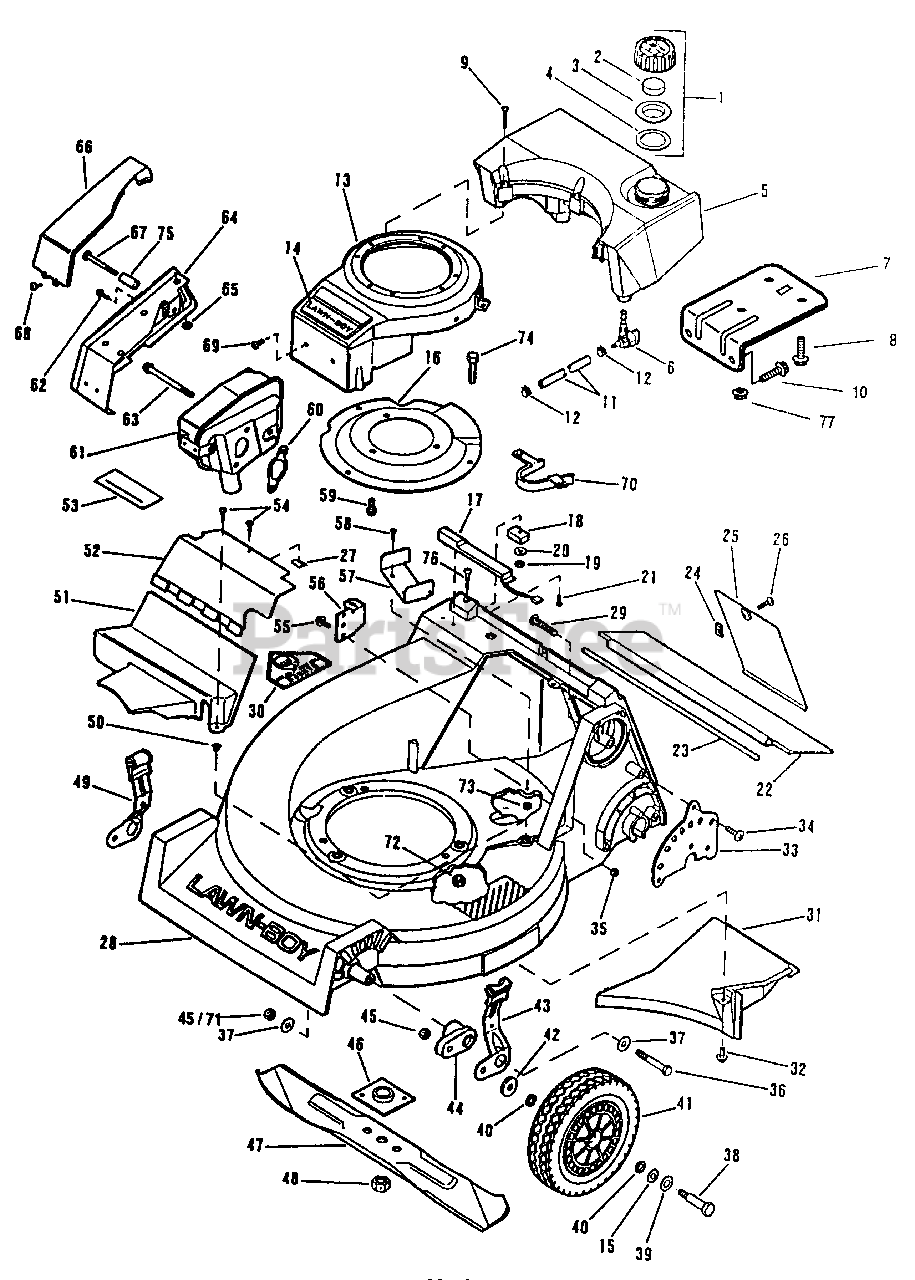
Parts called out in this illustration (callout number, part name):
1	Fuel Cap Assembly
2	Baffle
3	Cover
4	Gasket
5	Fuel Tank
6	Fuel Shut-Off Valve
7	Fuel Tank Mounting Bracket
8	Screw
9	Screw-Fuel Tank
10	Screw-Fuel Tank Bracket to Block
11	Fuel Line
12	Clamp-Fuel Line
13	Shroud and Applique Assembly
14	Applique
15	Washer-Shim
16	Engine Mounting Plate
17	Switch Assy-Bag Lock (ZMRC & D)
18	Magnet Assembly
19	Nut
20	Lockwasher
21	Screw (ZMRB & C)
22	Trailing Shield
23	Rod-Trailing Shield
24	Speed Nut
25	Access Door
26	Screw
27	Speednut
28	Housing Assy (ZMRB & D)
28	Housing Assy (ZMRC)
29	Handle Mounting Bolt
30	Decal-Blade Contact Warning
31	Baffle-Chute Floor
32	Screw
33	Height Adjust Plate
34	Screw
35	Nut
36	Screw
37	Washer
38	Bolt-Wheel
39	Washer-Wheel Bolt
40	Felt Washer
41	Wheel and Tire Assembly-Front
42	Washer
43	Knob and Spring Assembly-L.H.
44	Front Height Adj Arm (ZMRB & D)
45	Nut (ZMRC & D)
46	Collar and Plate
47	21" Blade
48	Nut-Blade
49	Knob and Spring Assembly-R.H.
50	Grommet
51	Lower Drive Cover
52	Upper Drive Cover w/Decal
53	Decal-Warning
54	Screw-Drive Cover (ZMRC & D)
55	Screw
56	Cable Anchor
57	Belt Guide
58	Screw
59	Screw-Mounting Plate to Engine
60	Exhaust Gasket
61	Muffler
62	Screw-Muffler Guard
63	Screw-Muffler
64	Muffler Guard Assembly
65	Pushnut
66	Muffler Cover
67	Screw-Muffler Guard
68	Screw-Muffler Guard
69	Screw-Shroud
70	Belt Snubber
71	Nut (ZMRC & D)
72	Locknut-Mting Plate to Housing
73	Locknut-Belt Guide to Housing
74	Screw-Mting Plate to Housing
75	Spacer-Muffler Guard
76	Screw (ZMRB)
76	Screw (ZMRC & D)
77	Nut-Hex Flange
